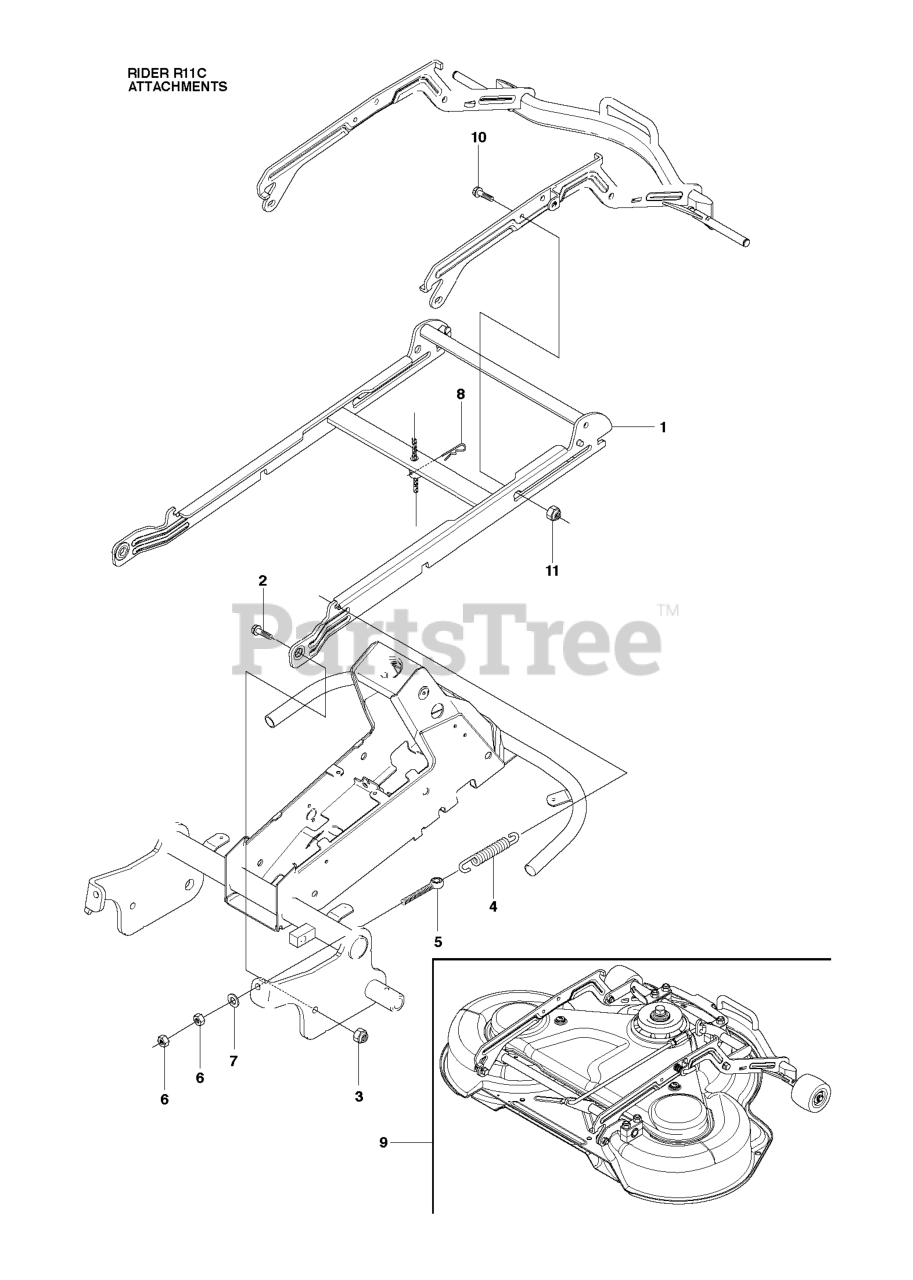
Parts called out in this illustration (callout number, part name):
6	NUT
7	WASHER
10	COLLAR SCREW
11	LOCKNUT M8
